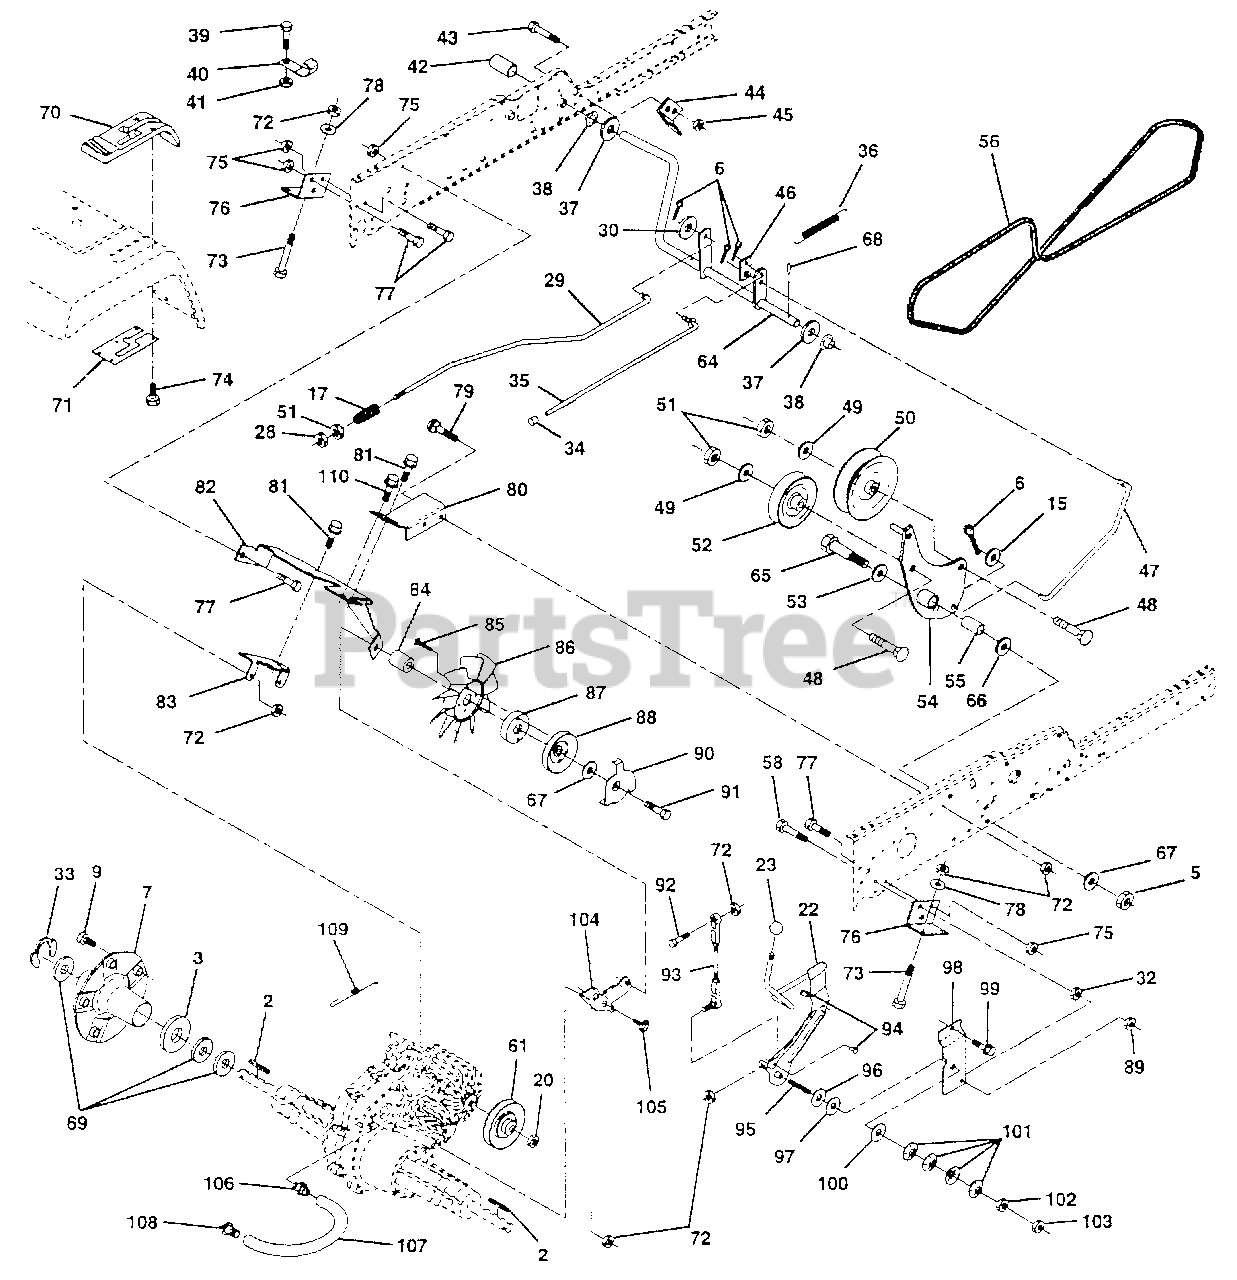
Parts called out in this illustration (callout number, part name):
1	KEY 1/4 X 2.5
2	WASHER T
6	COTTER PIN
7	HUB WHEEL ASM
8	E RING HYT
9	BOLT.HUB.WHL.REAR
17	SPRING ROD BRAKE
22	SHAFT ARM ASM
23	KNOB.DUCKHEAD.1/2
25	WASHER
29	ROD BRAKE
30	WASHER
34	PLUNGER CAP T
35	ROD BRAKE PART GT
37	WASHER
38	NYLINER T
39	SCREW
40	ACT-SWITCH T
42	PEDAL COVER T
43	BOLT LT
44	BRKT SWITCH GT
45	NUT
46	RETAINER SPRING
47	ROD.CLUTCH
48	BOLT
49	WASHER
50	FLAT IDLER PULLEY
51	NUT
52	PULLEY.IDLER.V.GR
53	WASHER T
54	ARM.ASM.IDLER.CLU
55	"LY, BEARING"
56	BELT-V 84.5
58	BOLT
59	NUT
61	PULLEY TRANSAXLE
62	NUT
63	BOLT FIN HEX 5/16
65	AXLE BOLT
66	WASHER.HARD.BLADE
67	WASHER
68	ROLL PIN STD
69	WASHER T
71	PLATE CONSOLE S
74	SCREW HEXWSH H-L
75	NUT.7/16
76	BRACKET TRAN VGTH
77	BOLT
78	WASHER
79	BOLT
80	BRACKET TORQUE RH
81	SCREW
83	STRAP TORQUE MID
84	SPACER
85	SCREW YTV
86	"FAN 7"" HYDRO"
87	ADAPTER FAN
89	WASHER
90	KEEPER BELT
91	SCREW.HXWSH.3/8
93	LINK ASM SHIFT
94	XMAS TREE FASTNER
95	SCREW SET 5/16
96	WASHER NICKEL PLT
97	BEARING THRUST
98	BRACKET SHIFT
99	SCREW LT
100	WASHER COMPRESSIN
101	WASHER
102	NUT HEX NYLOCK
103	JAM NUT TI
104	BRACKET IDLER
105	SCREW CRT
109	SPRING BRAKE
110	NUT
111	HINGE SCREW
112	NUT GTV
